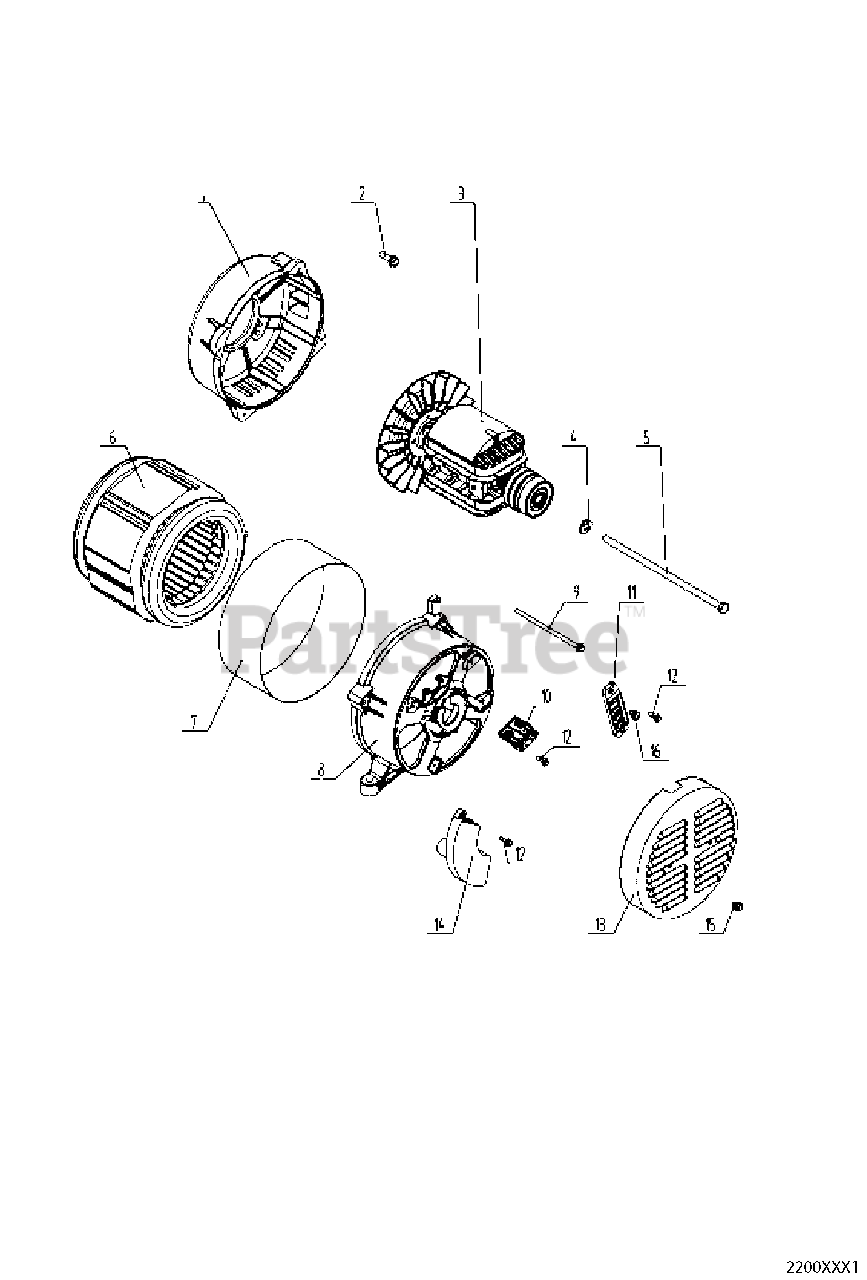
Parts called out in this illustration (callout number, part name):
2	HEXAGON FLANGE BOLT M8X25
5	HEXAGON BOLT M10X260
15	HEXAGON BOLT M6X10
